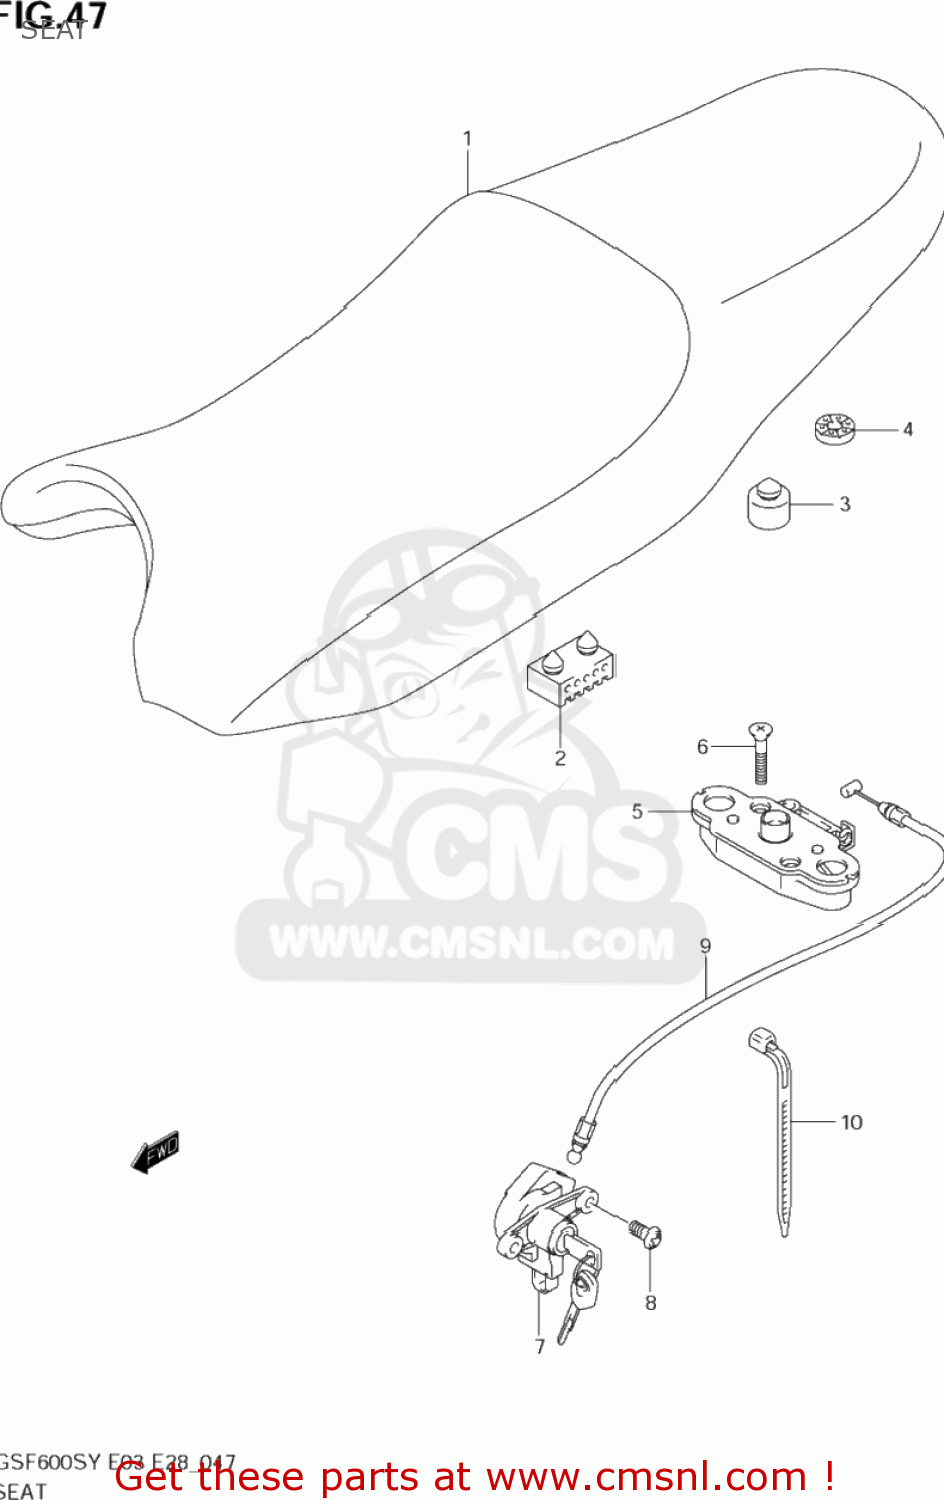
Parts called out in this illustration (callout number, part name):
1	SEAT ASSEMBLY
2	CUSHION,SEAT(40X20X15)
3	CUSHION
4	CUSHION
5	BRACKET,SEAT SUPPORT,RIGHT
6	SCREW
7	LOCK SET,SEAT & HELMET
8	SCREW(6X14)
9	CABLE,TANK LOCK
10	CLAMP(L:125)
